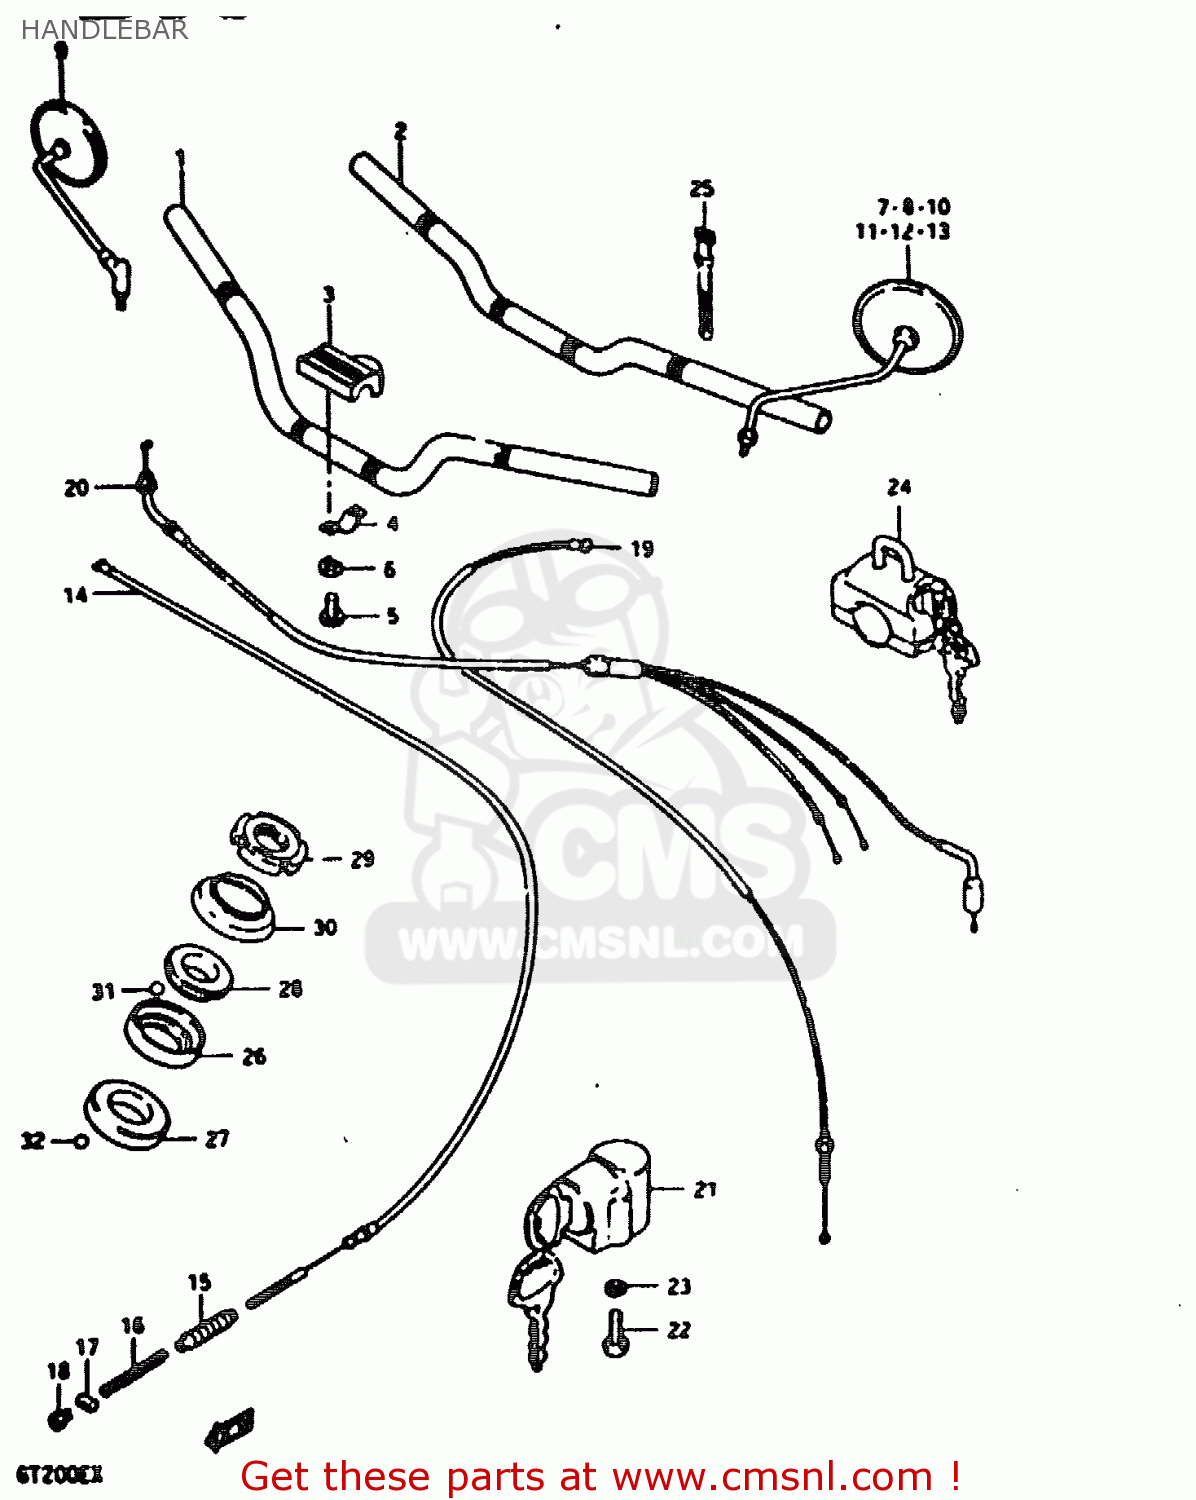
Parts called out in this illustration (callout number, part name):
1	HANDLEBAR (NEUTRAL HANDLE)
2	HANDLEBAR (FLAT HANDLE)
3	COVER, STEERING HEAD
4	BRACKET
5	SCREW
6	LOCK WASHER
9	MIRROR ASSY,RH
14	CABLE, FRONT BRAKE
15	SEAL,DUST(8X17X72)
16	SPRING
17	PIN
18	NUT
19	CABLE, CLUTCH
20	CABLE, THROTTLE
21	LOCK ASSEMBLY,STEERING
22	SCREW
23	LOCK WASHER
24	LOCK ASSEMBLY,HELMET
25	CLAMP(L:120)
26	RACE,STEERING INNER UPR
27	LACE,STEERING INNER LWR
28	RACE,STEERING OUTER UPR
29	NUT,STEERING STEM(25X44X10)
30	DUST SEAL,STEERING UPR
31	BALL
32	BALL
